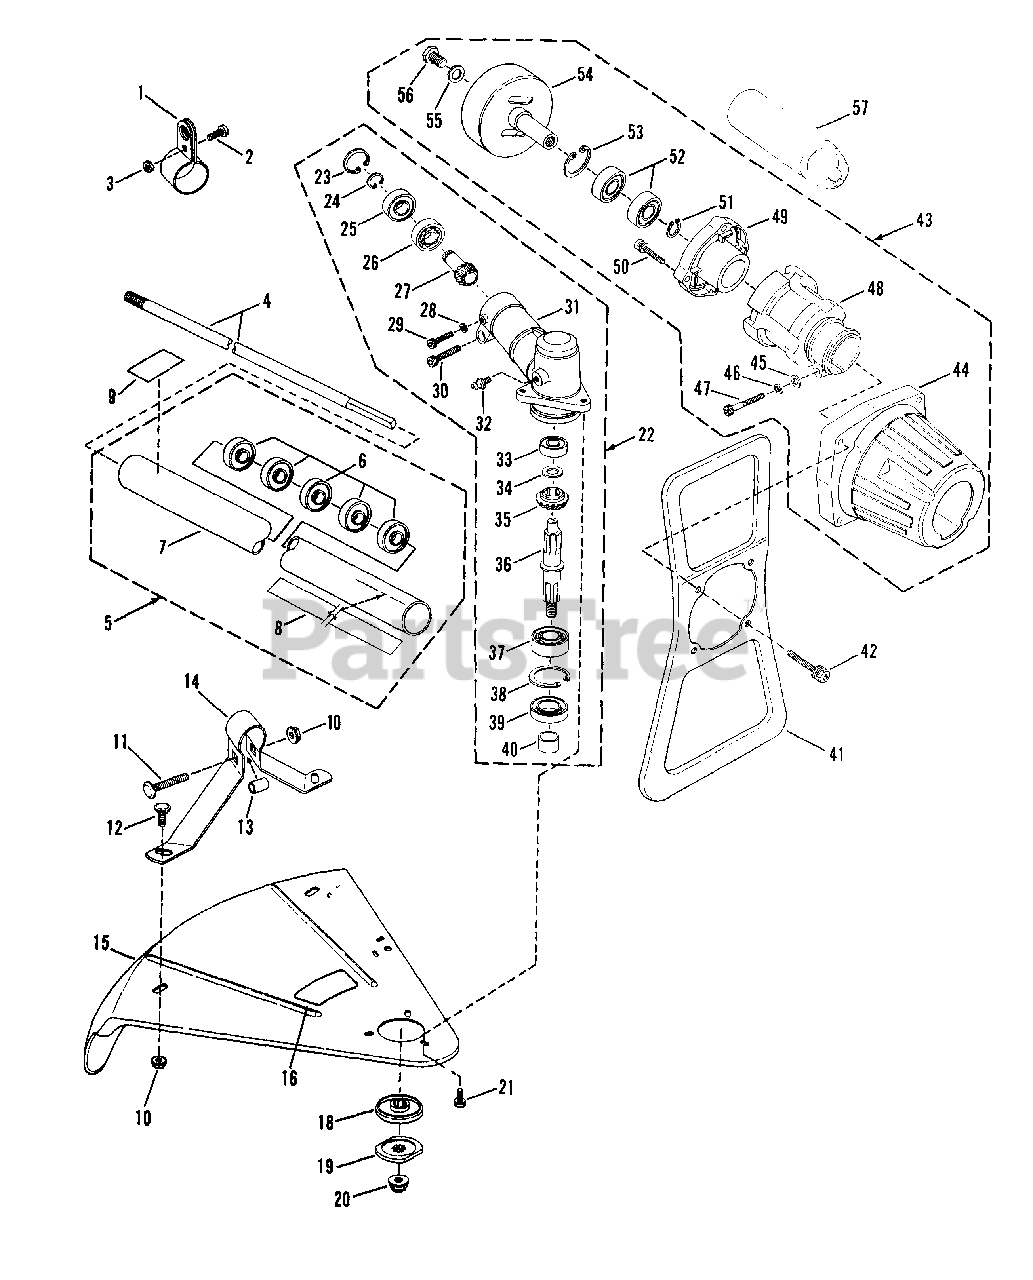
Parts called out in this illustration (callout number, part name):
1	HANGER BAND
2	SCREW, #10-32 x 3/8" P.H.S. Torx
3	LOCKNUT, #10x32 Hex
4	SHAFT, Tubing (60.58" x .3125", .235" Square End x 1", M8x1.25 x .56" Thread End
5	TUBE/DECAL ASSM'Y.
6	BUSHING
7	TUBING
8	DECAL, Model-Caution
9	LABEL, Serial
10	LOCKNUT, 5/16-18 Hex
11	SCREW, 5/16 Cx 1-1/2"
12	CARRIAGE BOLT, 5/16 Cx 1/2"
14	BRACE, Shield
15	SHIELD, Steel
16	LABEL, Direction
18	HOLDER (A)
19	HOLDER (B)
20	LOCKNUT, M10
21	BOLT, M5 x 10mm, Hex
22	GEAR HEAD ASSM'Y.
23	SNAP-RING
24	SNAP-RING
25	BEARING
26	BEARING
27	BEVEL PINION/SQ. DR.
28	LOCKWASHER
29	SCREW, M5 x 15mm, Socket
30	SCREW, M6 x 20mm, Socket
31	GEAR CASE
32	FITTING, Lube
33	BEARING
34	WASHER, Thrust
35	BEVEL GEAR
36	SPLINE SHAFT
37	BEARING
38	SNAP-RING
39	SEAL, Oil
40	SPLINE SLEEVE
42	BOLT, M6 x 35mm, Hex
43	CLUTCH CASE ASSM'Y.
44	CASE, Clutch
45	WASHER, Plain, M6
46	LOCKWASHER, M6
47	SCREW, M6 x 25mm
48	RING, Insert
49	COVER, Clutch Bearing
50	SCREW, M5 x 22mm
51	SNAP-RING, M15
52	BEARING
53	SNAP-RING, M35
54	DRUM, Clutch
55	WASHER, Plain, M8
56	BOLT, Low Head, M8
57	PROTECTOR/HIP PAD
